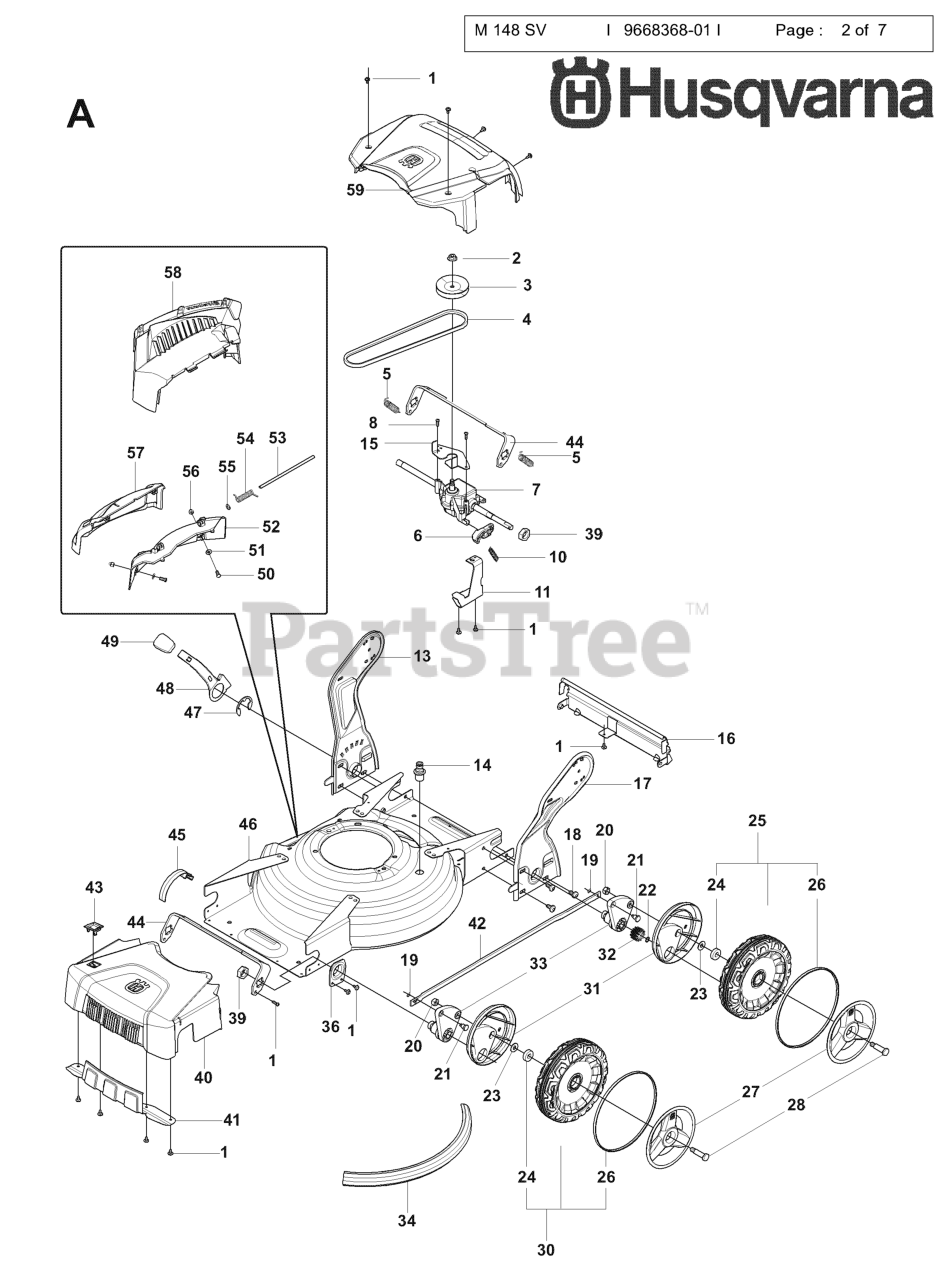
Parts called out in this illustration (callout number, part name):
1	SCREW ITXPANT T50X16 ZN/FE (A
4	BELT WRAPPED V-BELT Z 29.5
8	SCREW ITXPANT T50X16 ZN/FE (A
19	FASTENER
24	BALL BEARING
46	CHASSIS 48S A009 PAINTED
59	REAR COVER A009-2
